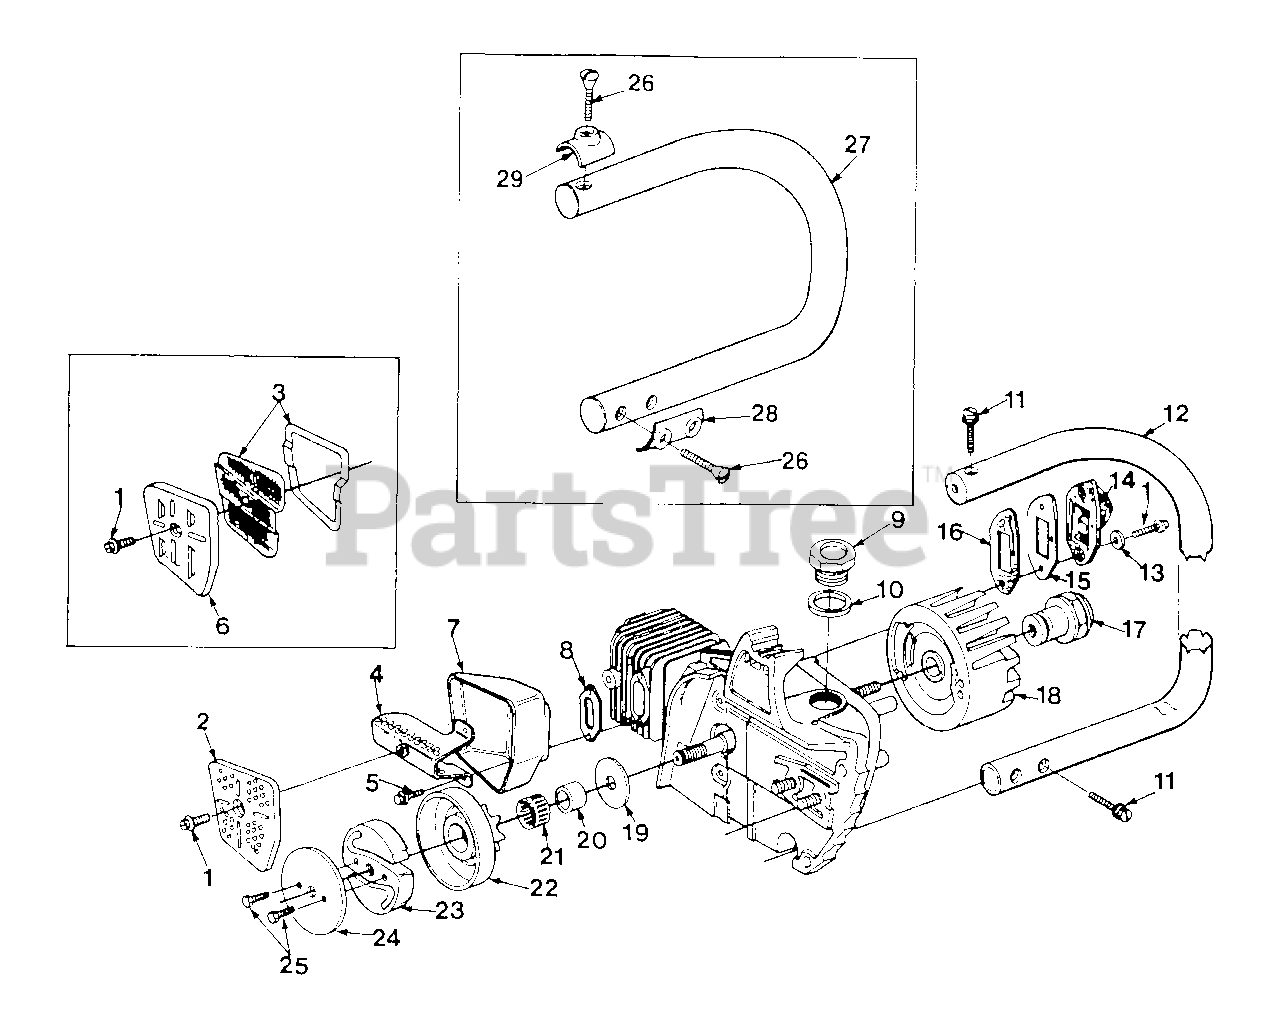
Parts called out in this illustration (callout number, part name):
1	SCREW- Hex washer hd., 8-32 x 1/2
2	CAP- Muffler (150 AO)
3	ARRESTOR- Spark (150 AOW)
4	BAFFLE- Muffler
5	SCREW- Hex washer hd., 8-32 x 3/8
6	CAP- Muffler (150 AOW)
7	BODY- Muffler
8	GASKET- Muffler
9	CAP- Oil filler
10	GASKET- Oil filler cap
11	SCREW- Oval hd., 10-24 x 1 1/8
12	HANDLE BAR
13	WASHER- Flat 7/16 x 3/16 x 1/16
14	MANIFOLD- Intake
15	COVER- Pulse
16	GASKET- Intake manifold
17	NUT- Rotor
18	ROTOR (point ignition)
18	ROTOR (Solid state)
19	WASHER- Thrust
20	RACE- Inner
21	BEARING- Needle
22	SPROCKET & DRUM- 7 tooth, 3/8" pitch
23	CLUTCH "S"
24	PLATE- Clutch
25	SCREW- Hex hd., 10-32 x 1/2
26	SCREW- 10-24 x 1 5/8 (150 E)
27	HANDLE BAR (150 E)
28	CLAMP- Handle bar (lower)
29	CLAMP- Handle bar (upper)
